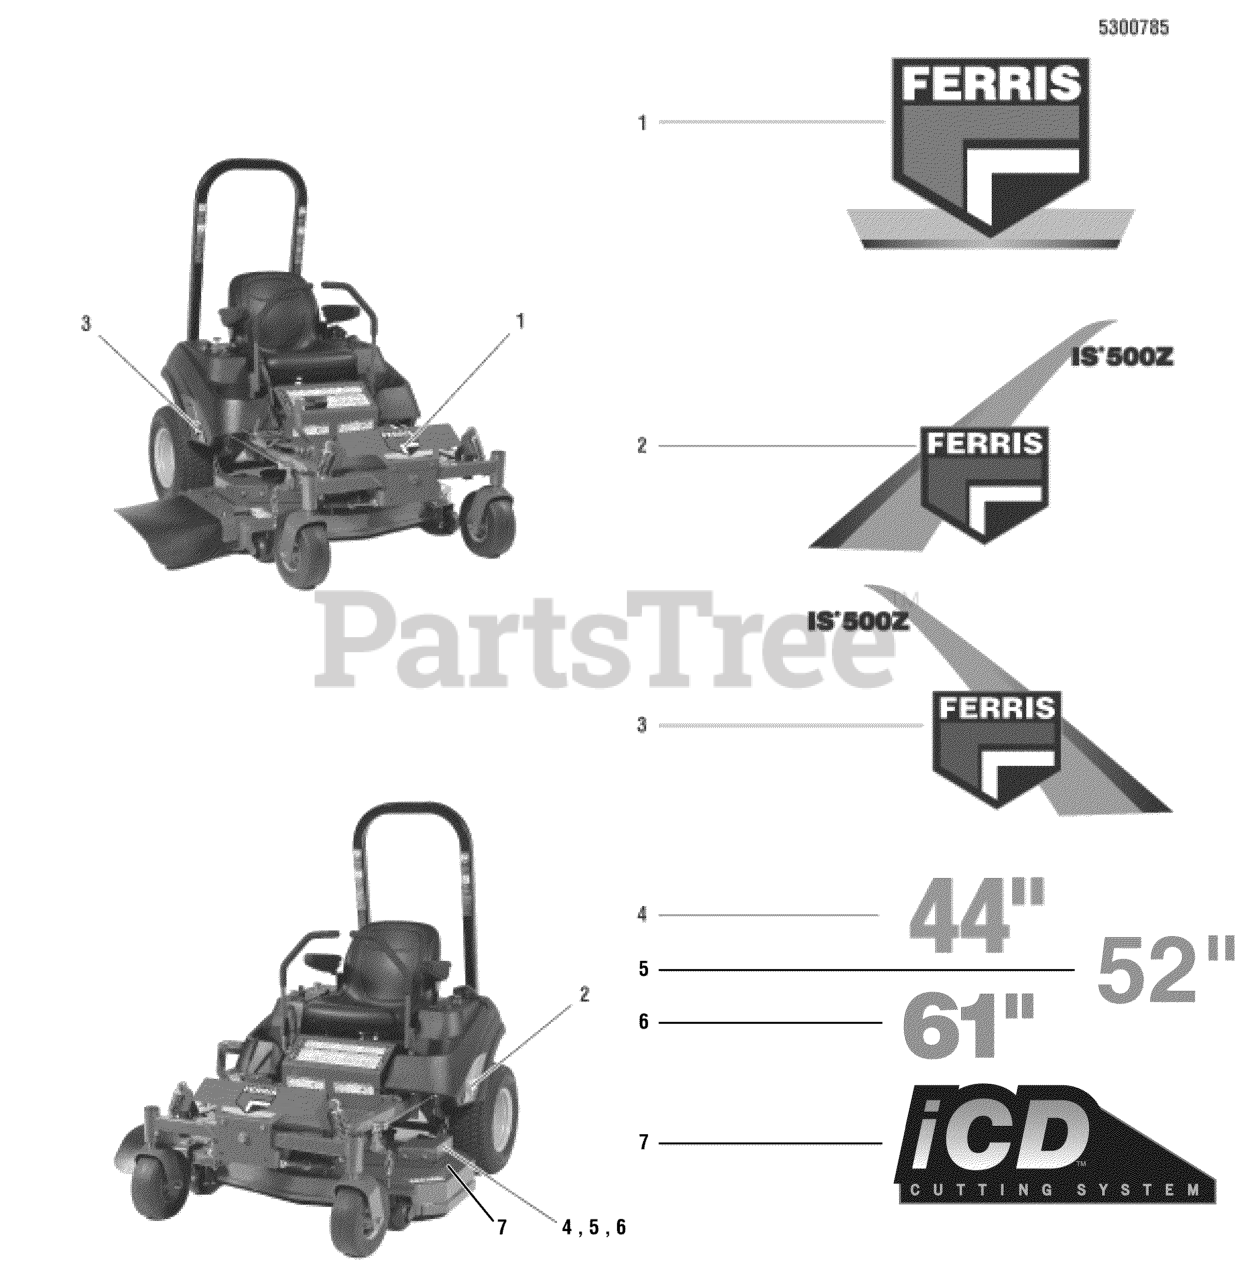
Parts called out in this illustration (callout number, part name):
1	DECAL, BADGE, FERRIS, LOGO, 3" X 6.2"
2	DECAL, BADGE, IS500Z - LH
3	DECAL, BADGE, IS500Z - RH
4	DECAL, 44
5	DECAL, 52
6	DECAL, 61
7	DECAL, iCD CUTTING SYSTEM
